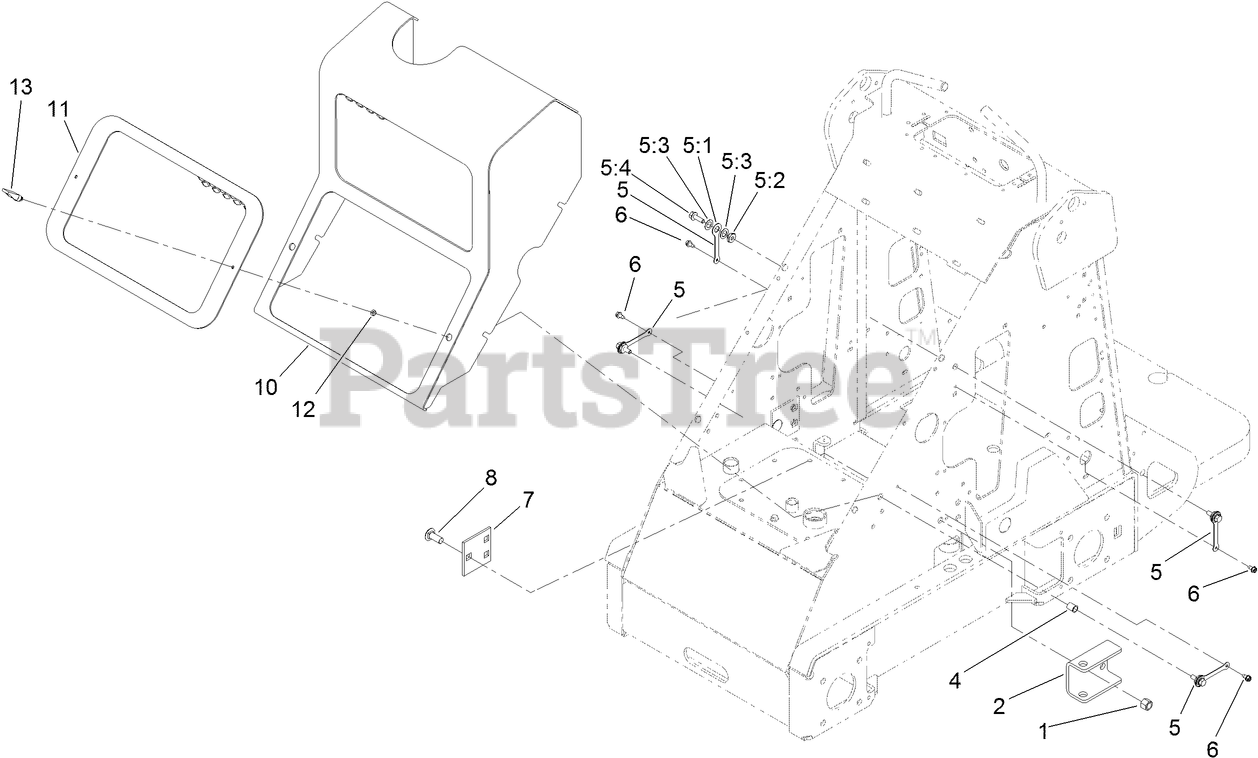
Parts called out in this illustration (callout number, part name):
1	NUT-LOCK, NI
2	BRACKET-ANCHOR
4	INSERT-THREADED
5	LANYARD ASM
5:1	LANYARD-3 INCH
5:2	NUT-SHOULDER
5:3	WASHER
5:4	SCREW-HHF
6	SCREW-HWH
7	PLATE-ANCHOR
8	SCREW-CARR, SHORT NECK
12	WASHER
13	LATCH-SWELL
